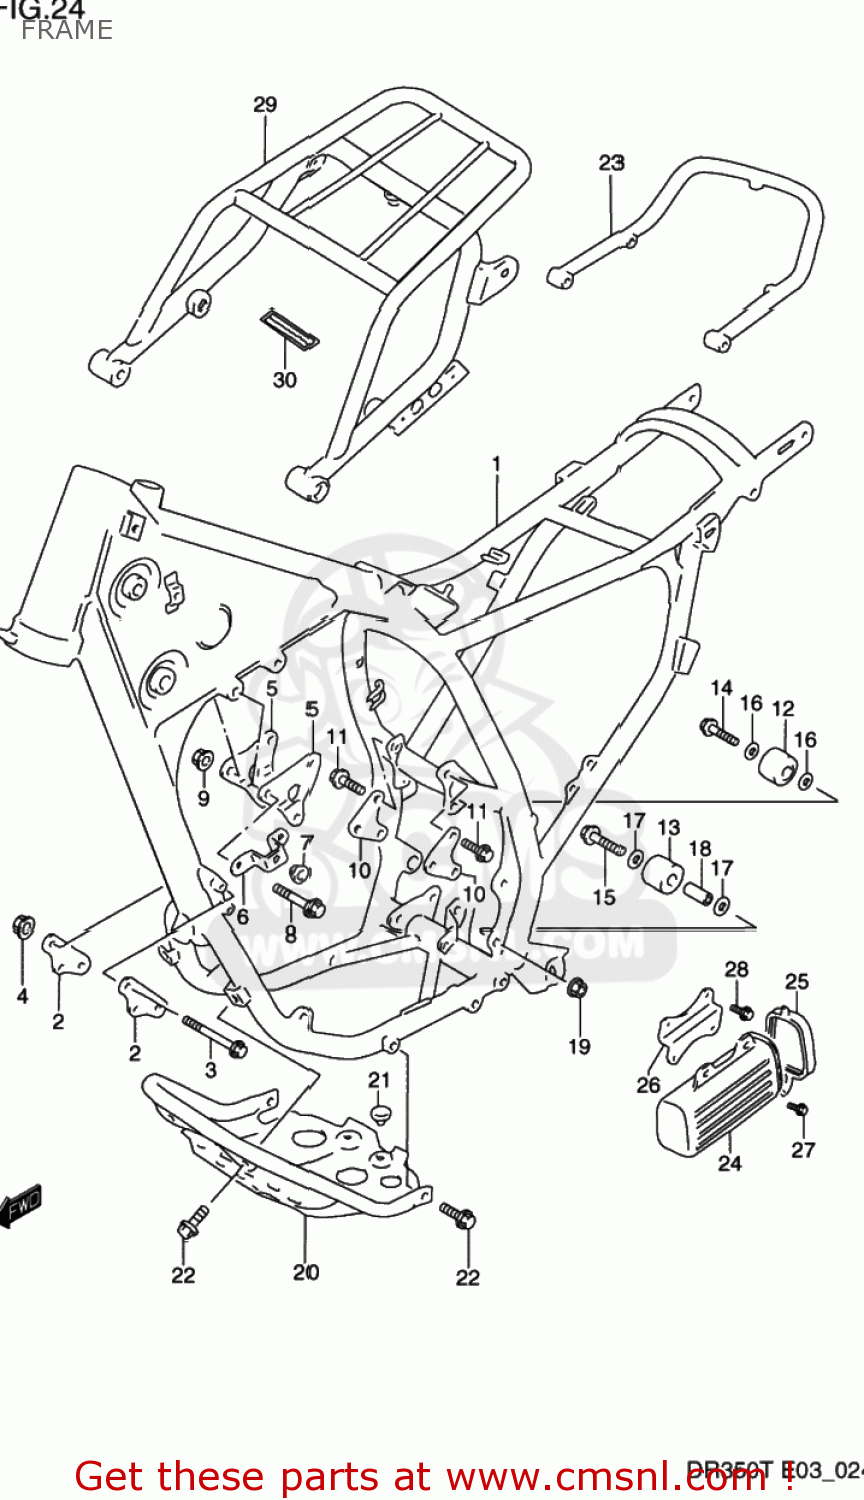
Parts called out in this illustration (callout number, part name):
1	FRAME
2	PLATE,ENGINE MOUNT FR
3	BOLT
4	NUT
5	PLATE,ENGINE MOUNT UPR
6	PLATE,FUEL TANK STOPPER
7	CUSHION
8	BOLT(8X70)
9	NUT
10	PLATE,ENGINE MOUNTING,REAR
11	BOLT(8X16)
12	ROLLER,CHAIN
13	ROLLER,CHAIN CONTROL
14	BOLT(8X38)
15	BOLT
16	WASHER
17	WASHER
18	SPACER (8.6X13.8X28)
19	NUT
20	PROTECTOR,ENGINE
21	CUSHION
22	BOLT
23	GRIP,RR
24	HOLDER,TOOL
25	CAP,TOOL HOLDER
26	PLATE,TOOL HOLDER FITING
27	BOLT 6X16
28	BOLT
29	CARRIER,SPORT
30	LABEL,WARNING
